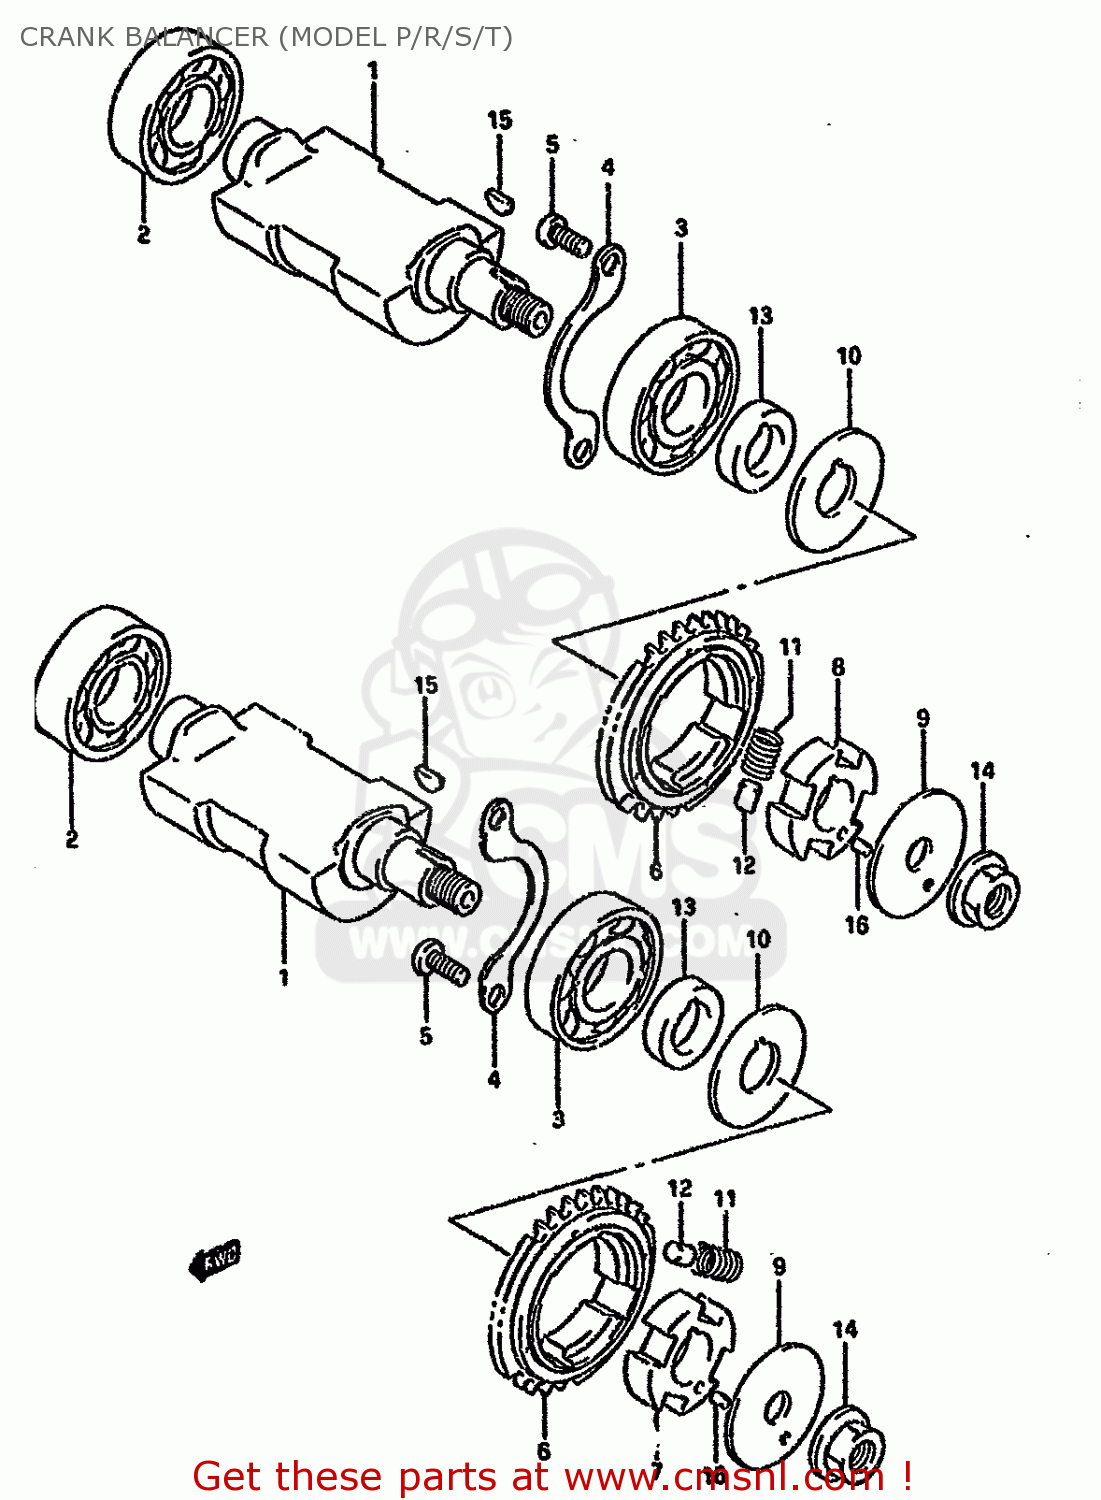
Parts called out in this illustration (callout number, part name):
1	BALANCER,CRANK
2	BEARING(20X42X12)
3	BEARING(20X47X12)
4	RETAINER,CRANK BAL BEARING
5	SCREW
6	SPROCKET,CRANK BAL DRIVEN
7	RACE,BALANCER DRIVER SPOCKET,INNER
8	RACE,BALANCER DRIVER SPOCKET,INNER
9	WASHER (10X39X1.6)
10	WASHER
11	SPRING
12	PIN(6X8.8)
13	SPACER (16X26X7.5)
14	NUT
15	KEY
16	PIN(3X11.3)
